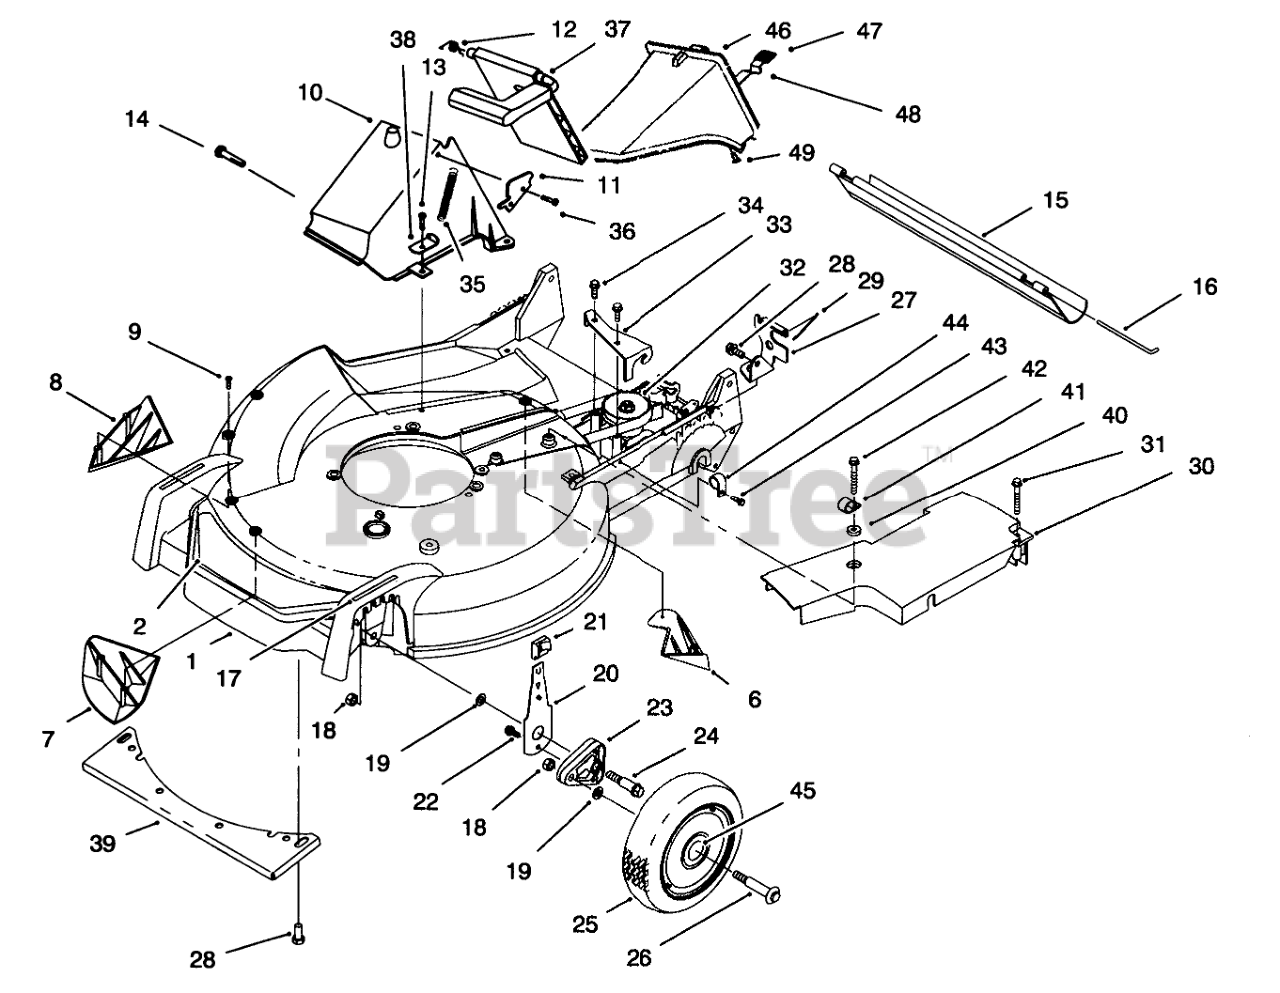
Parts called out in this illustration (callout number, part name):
1	Housing Assembly (Incl. Ref. #6-9, 17, 28, 39)
2	DECAL - DECK
6	KICKER-REAR
7	KICKER-FRONT
8	KICKER-RH
9	SCREW-PPH
10	TUNNEL-DISCHARGE
11	LATCH-PLATE
12	RETAINER-DOOR
13	SCREW-HWH
14	SCREW AND WASHER ASM
15	SHIELD-TRAILING
16	ROD-SHIELD
17	DECAL - HOC
18	NUT-LOCK
19	WASHER
20	FRONT SPRING ARM ASM
21	KNOB-ARM
22	SCREW-HWH
23	ARM-PIVOT, FRONT
24	BOLT-SHOULDER
25	Wheel-ASM
26	BOLT-WHEEL
27	Bracket-Adj. Trac
28	SCREW-HWHTF
29	RETAINER-CABLE
30	BELT COVER
31	SCREW-HHFTF
32	GEARCASE ASM
33	Bracket-Guide
34	SCREW-HWHTF
35	SPRING-DOOR
36	SCREW-PLASTITE
37	DISCHARGE DOOR ASM
38	BRACKET-SPRING
39	Shield-front
40	WASHER
41	CLAMP-CABLE
42	SCREW-SPECIAL
43	SCREW-HWH
44	CLAMP-CABLE
45	BUSHING
46	DISCHARGE PLUG ASM
47	GRIP-LATCH
48	LATCH-PLUG, DISCHARGE
49	RIVET-HEAD, FLAT
